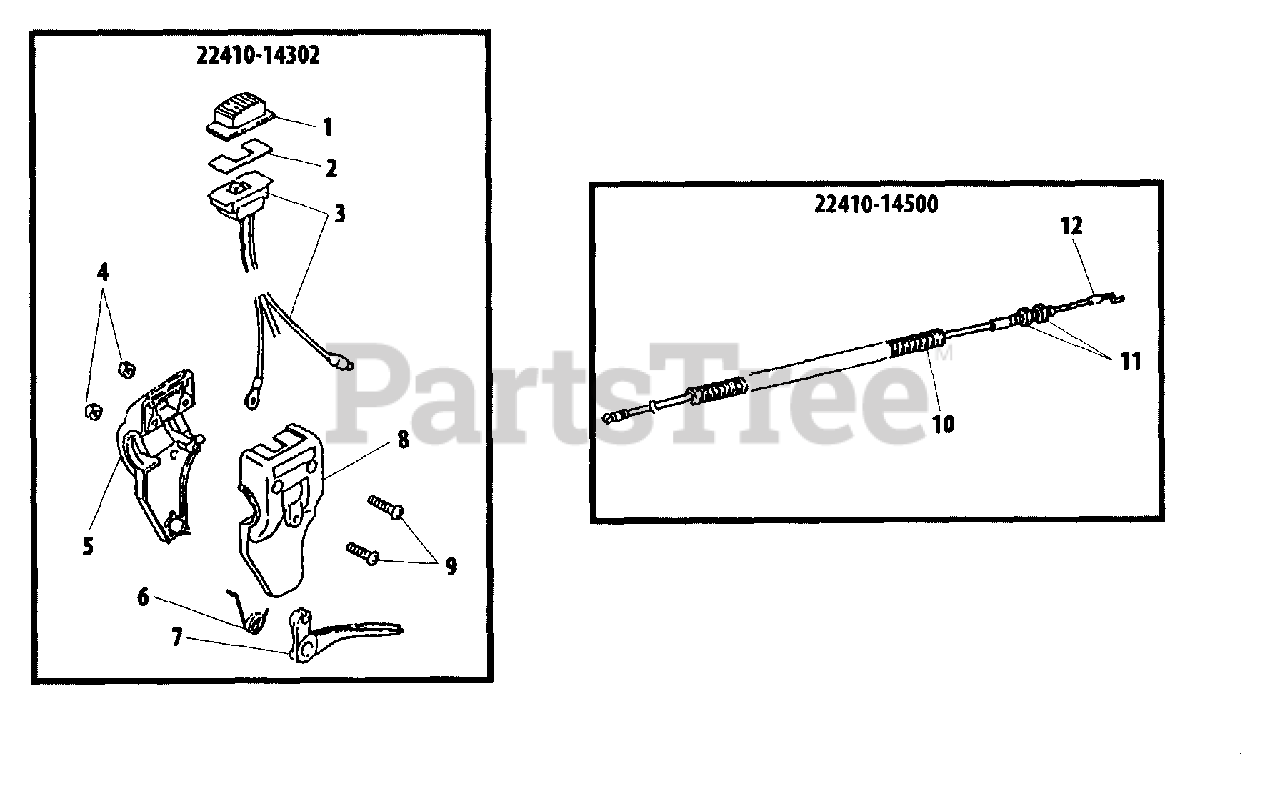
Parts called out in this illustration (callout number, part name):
1	KNOB, SWITCH
2	PLATE, SWITCH
3	SWITCH
4	NUT M5
5	CONTROL HANDLE - RIGHT
6	SPRING, RETURN
7	TRIGGER, THROTTLE
8	CONTROL HANDLE - LEFT
9	SCREW
10	TUBE, PLASTIC PROTECTIVE
11	NUT M6
12	CABLE, THROTTLE
22410-14302	THROTTLE CONTROL KIT
22410-14500	THROTTLE CABLE ASSY
